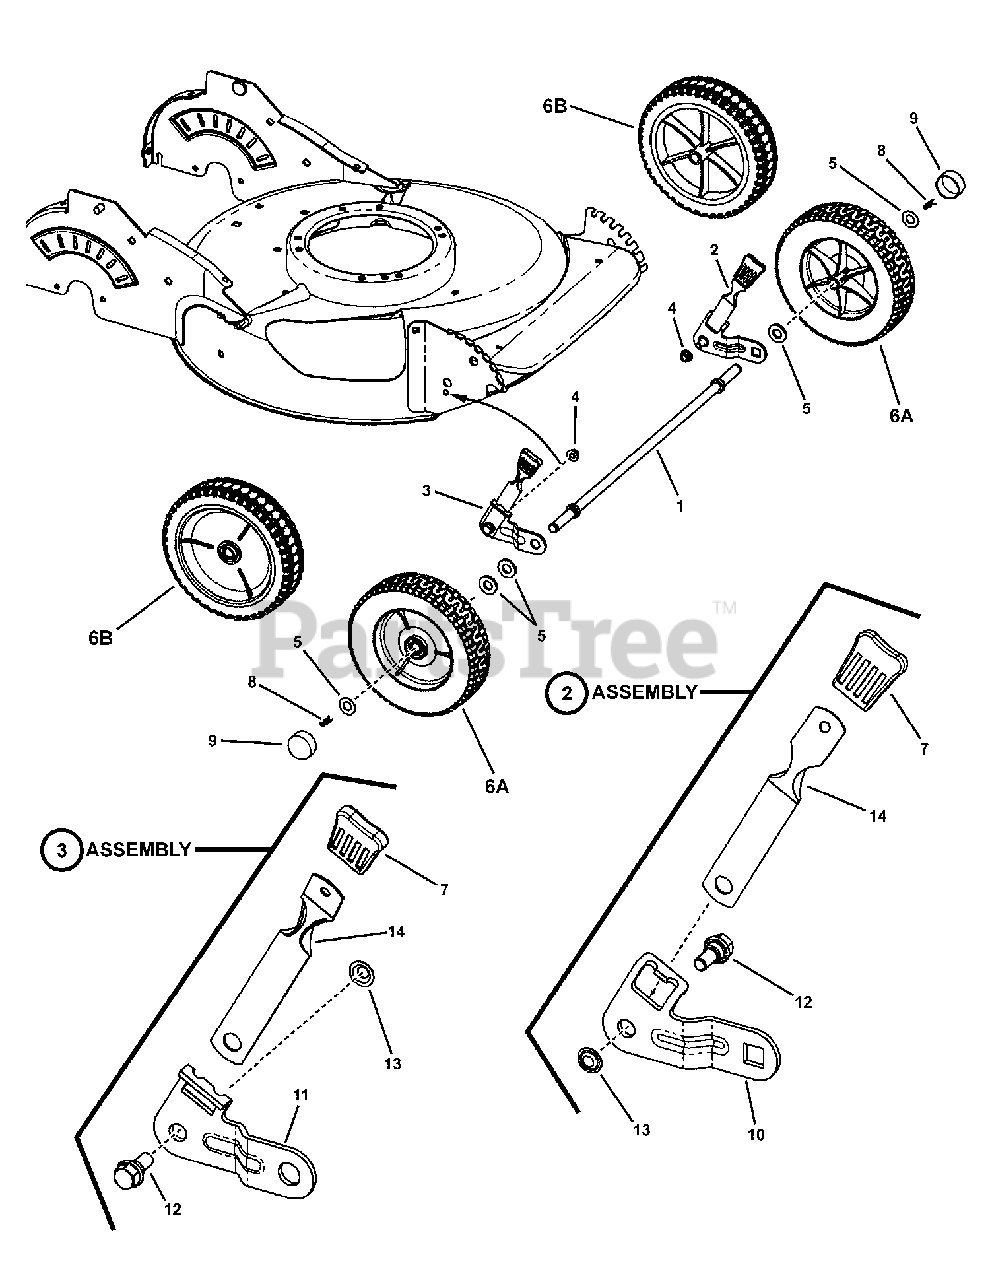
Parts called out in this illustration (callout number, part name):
1	AXLE, Front, Low Cost Walk Mower, 21
2	ASSEMBLY, Front Wheel Arm, L. H.
3	ASSEMBLY, Front Wheel Arm, R. H.
4	NUT, 5/16-18 Hex Flange Lock
5	WASHER, Shim, .875 x .531 x .060
6A	WHEEL, Front, 8", LS Tread, 1-5/8" Hub
6B	WHEEL, Front, 8 x 2, Double Bar II Tread, 1-5/8" Hub w/bushing
7	GRIP, Height Latch - Black (1.3" Wide)
8	COTTER, Hairpin
9	HUB CAP, 1-3/8" Dia.
10	FRONT WHEEL ARM, L.H. (Square Hole)
11	FRONT WHEEL ARM, R.H. (Round Hole)
12	SHOULDER BOLT, 5/16-18
13	BOLT RETAINER, 5/16- Black
14	HEIGHT LATCH V21
